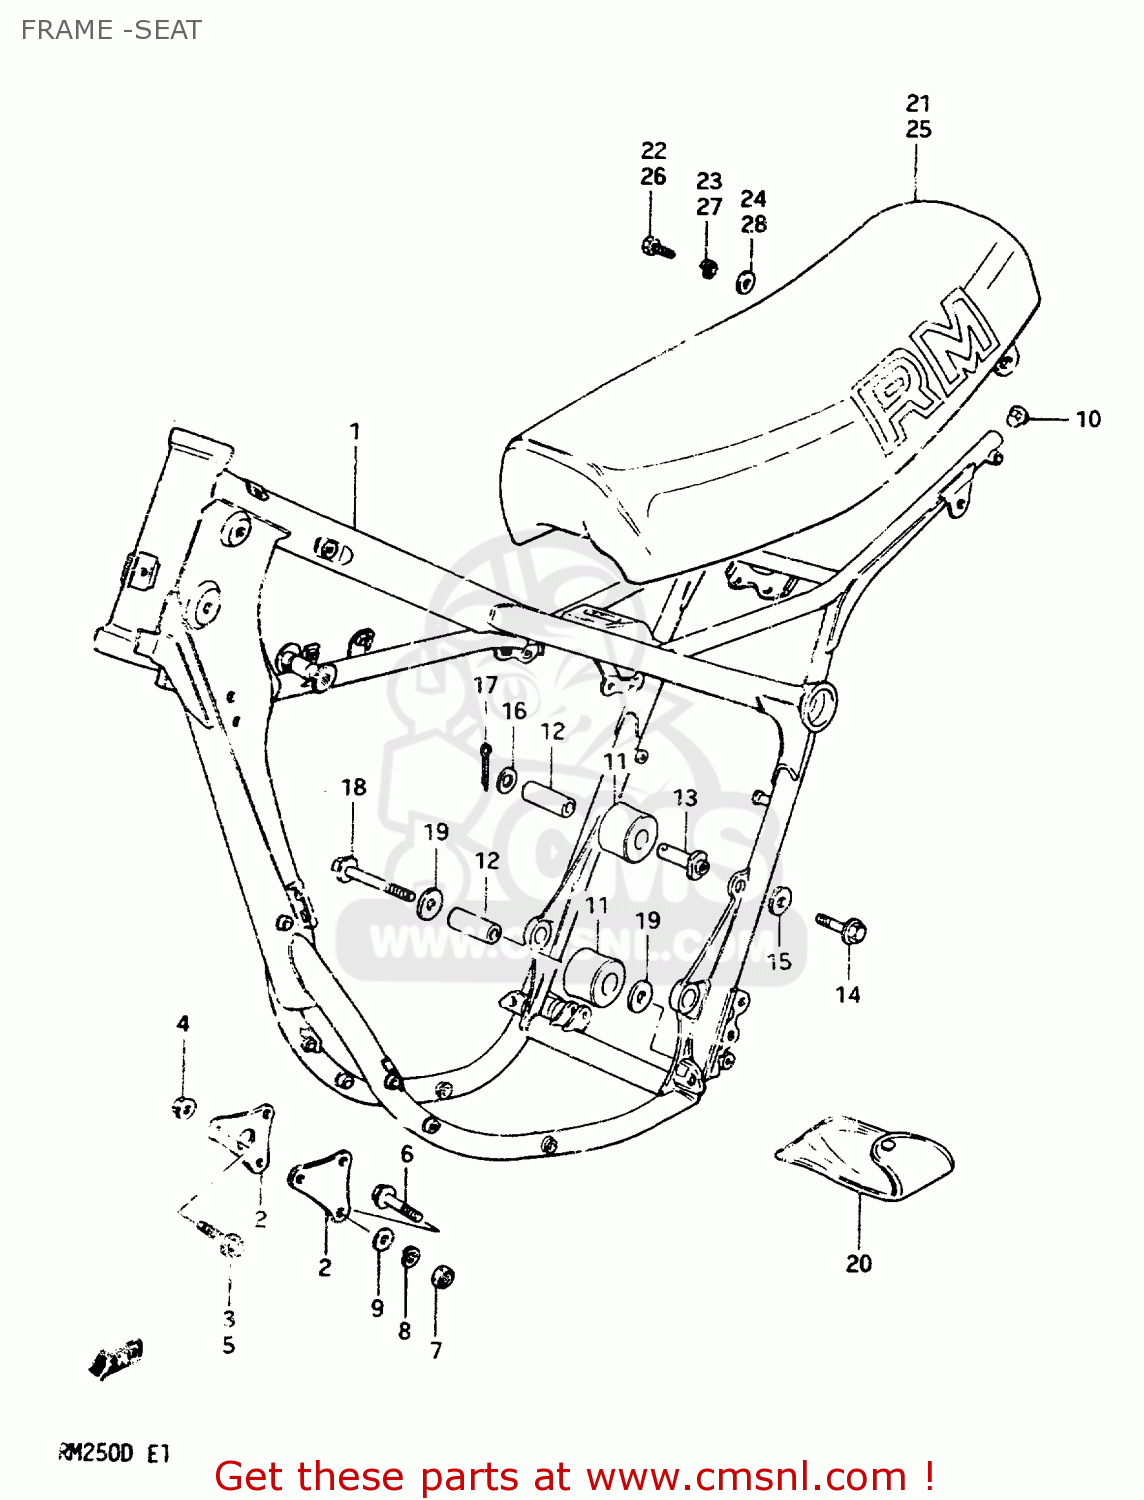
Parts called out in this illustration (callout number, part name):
1	FRAME
2	PLATE,ENGINE MOUNTING
3	BOLT 8X55
4	NUT
5	BOLT 8X55
6	BOLT
7	NUT
8	LOCK WASHER
9	WASHER
10	PLUG(OD:17)
11	ROLLER,CHAIN LENGTH CONTROL
12	SPACER,CHAIN LENGTH ROLLER
13	BOSS,CHAIN LENGTH ROLLER
14	BOLT 6X20
15	WASHER
16	WASHER
17	PIN 25X20
18	BOLT(8X45)
19	WASHER
20	TOOL SET
21	SEAT ASSEMBLY
22	BOLT
23	WASHER,LOCK
24	WASHER (8.5X20X2.6)
25	SEAT ASSEMBLY
26	BOLT
27	LOCK WASHER
28	WASHER
